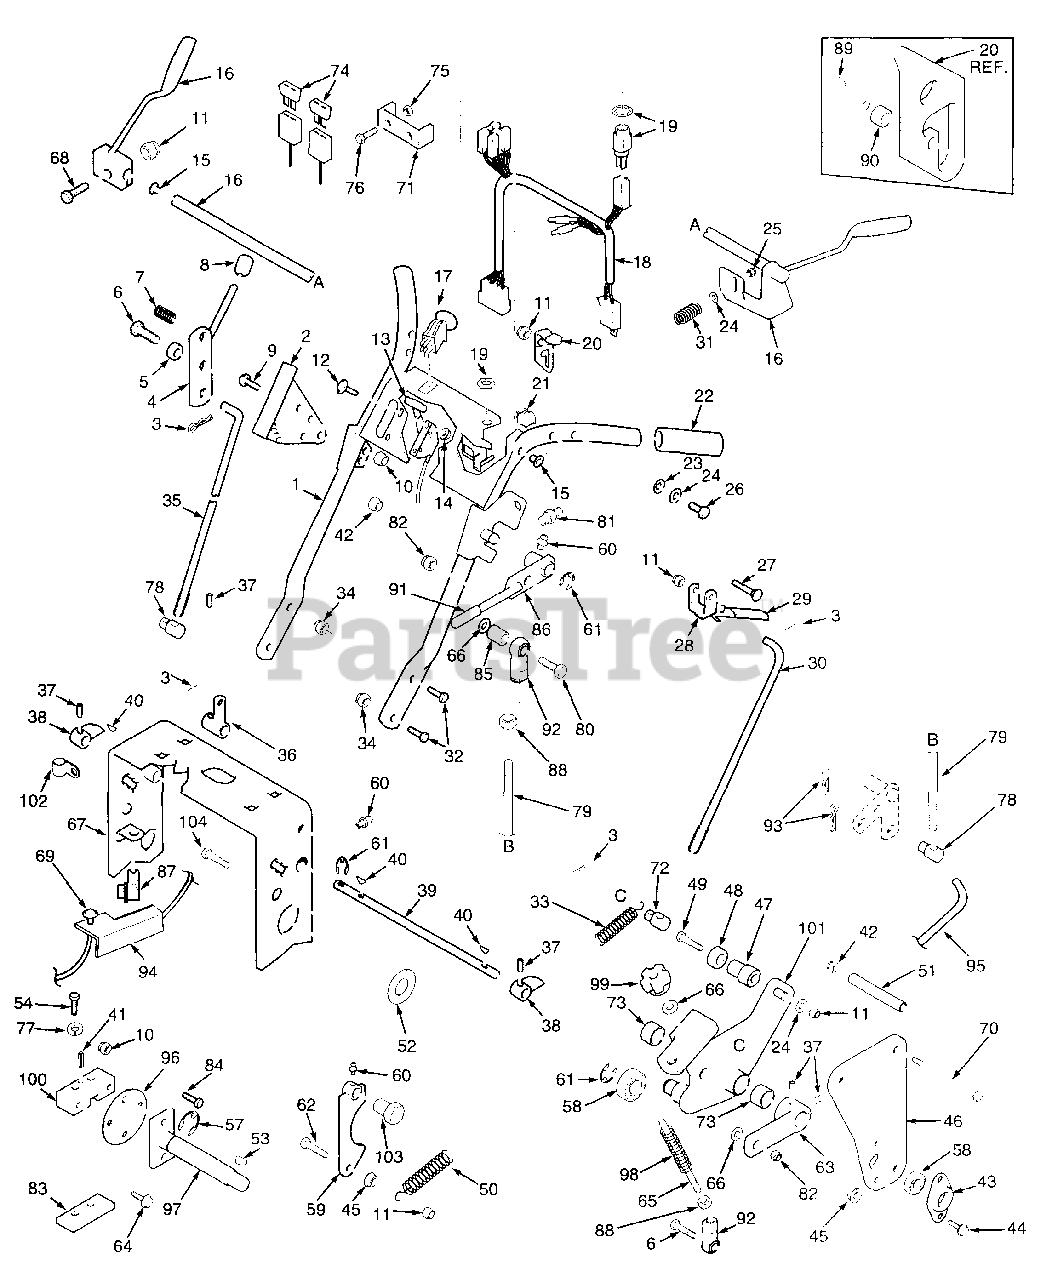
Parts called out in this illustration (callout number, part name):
1	Upper Handle Wlmt. W/Decals
2	Quadrant, Speed Control
3	Hairpin, .094 x 1.19
4	Lever, Speed Adjustment
5	Bushing, Speed Adjustment Lever
7	Ball Plunger
8	Knob, Speed Adjustment
9	Capscrew, 1/4-20 x 3/4" FHHS
10	Nut, 1/4-20 Elastic Stop
11	Nut, 5/16-18 Elastic Stop
12	Screw, #10-32 x 1/2" PW HD
13	Throttle Control
14	Nut, #10-32 Serr. Flange
15	Bushing
16	Handle, Oper. Presence-RH
17	Switch, Elec. Clutch Eng.
18	Wire Harness, Manual Start
19	Key Switch, Manual Srt.
20	Neutral Latch-RH
21	Switch, Neutral Interlock
22	Grip
23	Washer, Curved Spring
24	Flat Washer
25	Nut, 5/16-18 Elastic Stop
28	Lever, Steering Control
29	Grip, Steering Control
30	Rod, Steering Control
31	Spring Handle Return
32	Capscr 3/8-16 x 1" Ser. Flange
33	Spring
34	Nut. 3/8-16 Serr. Flange
35	Rod Speed Control
36	Bellcrank, Speed Control
38	Cam Speed Control
39	Jackshaft, Speed Control
40	Key 1/8 x 1/2" Woodruff
43	Flange, Bearing
44	Capscrew 5/16-18 x 1" Serr. Flg.
45	Nut, 5/16-18 Serrated Flange
46	Plate, Side
47	Support, Neutral Support
48	Bearing, Speed Ctrl. Bellcrank
50	Spring, Return
51	Spacer, Side Plate
52	Flat Wshr., 3/4-.766 x 1.25 x .035
53	Key, Woodruff, 3/16 x .75"
54	Bolt, Hex head, 1/4-20 x 1.25
56	Lock Washer, 5/16
57	Clip, Retaining .750 diameter
58	Bearing, Ball Neutral Return
59	Cam, Neutral
60	Grease Fitting, 1/4-28 UNF
61	Retaining Ring, 5/8 Ext. "E"
63	Lever, Speed Control
65	Stud, 3/8-16x4.5
66	Flat Wshr., 15/16 x .3906 x 12 ga
67	Deck, Engine
68	Hex Head Bolt, 5/16-18 x 1.25"
69	Choke Control
70	Bolt, Hex Head 3/8-16 x 4.25"
71	Fuse Holder
72	Swivel Joint, Steering Rod
73	Bushing
74	Blade Fuse, 20A
75	Nut, #10-32 Elastic Stop
76	Screw, #10-32 x 1.5" Phillips
77	Lockwasher, 1/4"
78	Swivel Joint
79	Rod, Brake Lever
80	Hex Hd. Bolt, 3/8-16 x 1.75"
81	Switch, Parking Brake
82	Nut, 3/8-16 Elastic Stop
83	Plate, Threaded
85	Spacer
86	Parking Brake Lever with Grip
87	Switch, Safety
88	Nut, 3/8-24
89	Bushing, Bearing Retainer
90	Bearing, Neutral Lock
91	Grip, Parking Brake
92	Ball Joint, RH Thread
93	Hairpin, .094 x 1.62"
94	Bracket, Choke Mtg.
95	Rod, Lower Brake
96	Plate, Coupler
97	Shaft, Pump Control
98	Spring
99	Knob, Tracking Adjustment
100	Block, Pump Control
101	Control, LH
102	Wire Loom
103	Bushing
104	Bolt, Hex Head 3/8-16x1.5
